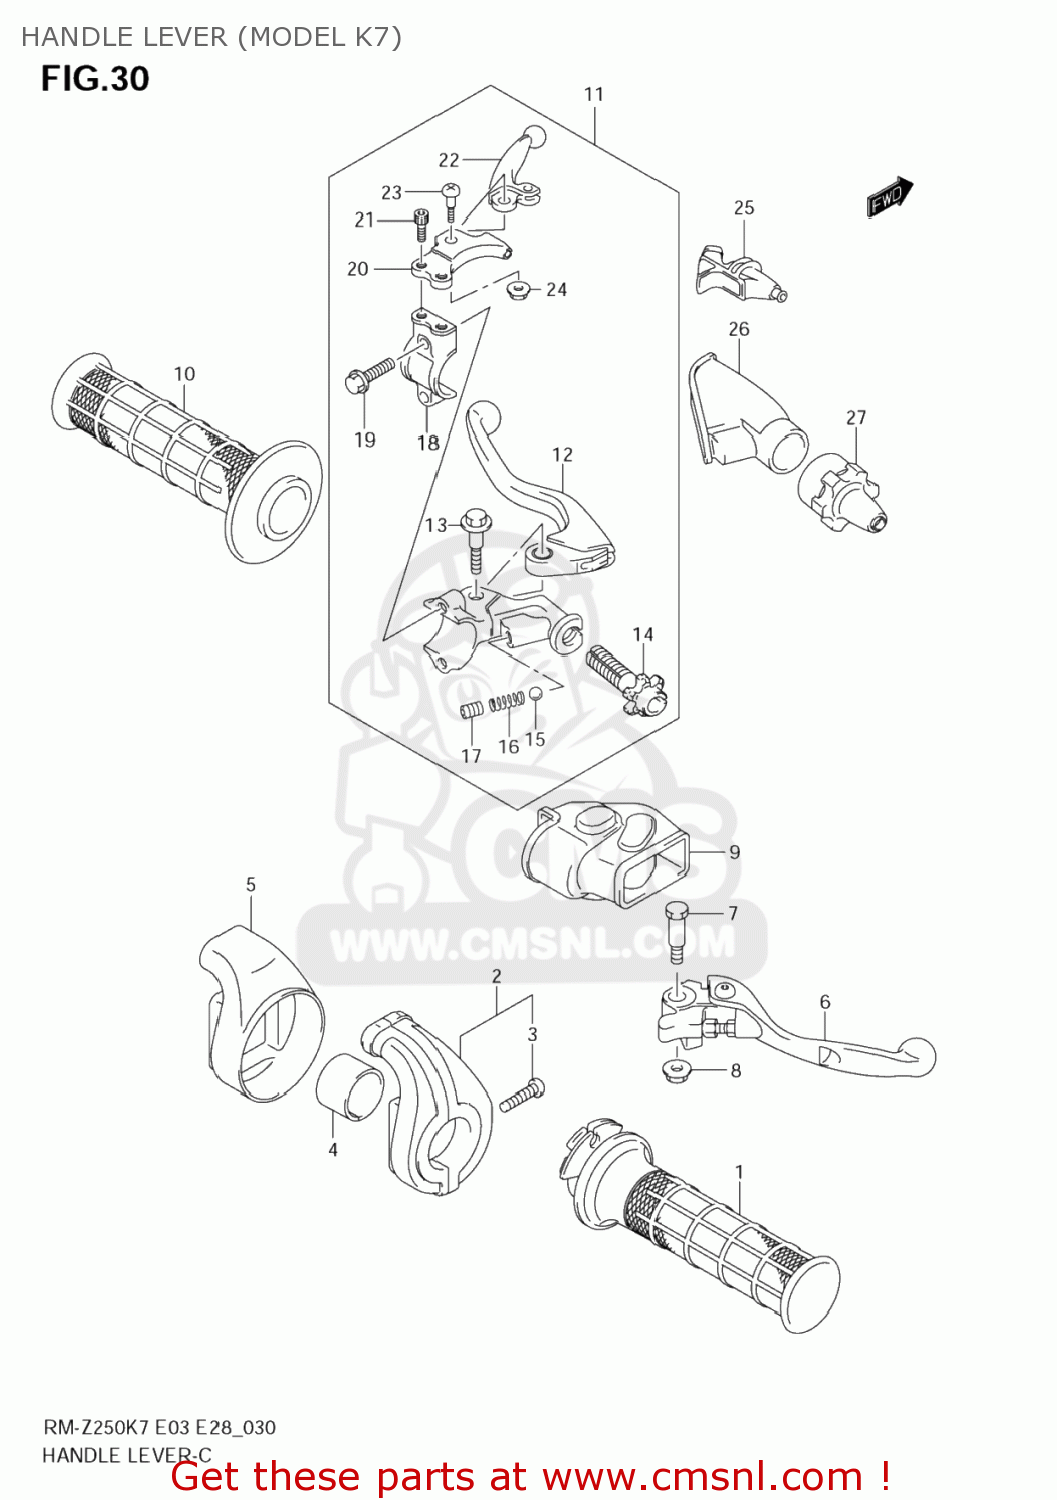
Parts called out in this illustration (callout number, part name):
1	GRIP COMP,THRO
2	CASE ASSY,THROTTLE
3	SCREW,CASE
4	COLLAR,THROTTLE CASE
5	COVER,THROTTLE CASE
6	LEVER ASSY,BRAKE
7	BOLT,BRAKE LEVER
8	NUT
9	COVER,BRAKE LEVER
10	GRIP,L
11	LEVER ASSY,CLUTCH
12	LEVER,CLUTCH
13	BOLT
14	ADJUSTER,CLUTCH CABLE
15	BALL
16	SPRING
17	SCREW(6X8)
18	HOLDER,CLUTCH LEVER
19	BOLT,BRACKET
20	HOLDER,HOT STARTER LEVER
21	SCREW(5X12)
22	LEVER,HOT STARTER
23	BOLT,HOT STARTER LEVER
24	NUT
25	COVER,HOT STARTER LEVER
26	COVER,CLUTCH LEVER
27	COVER,CLUTCH ADJUSTER
